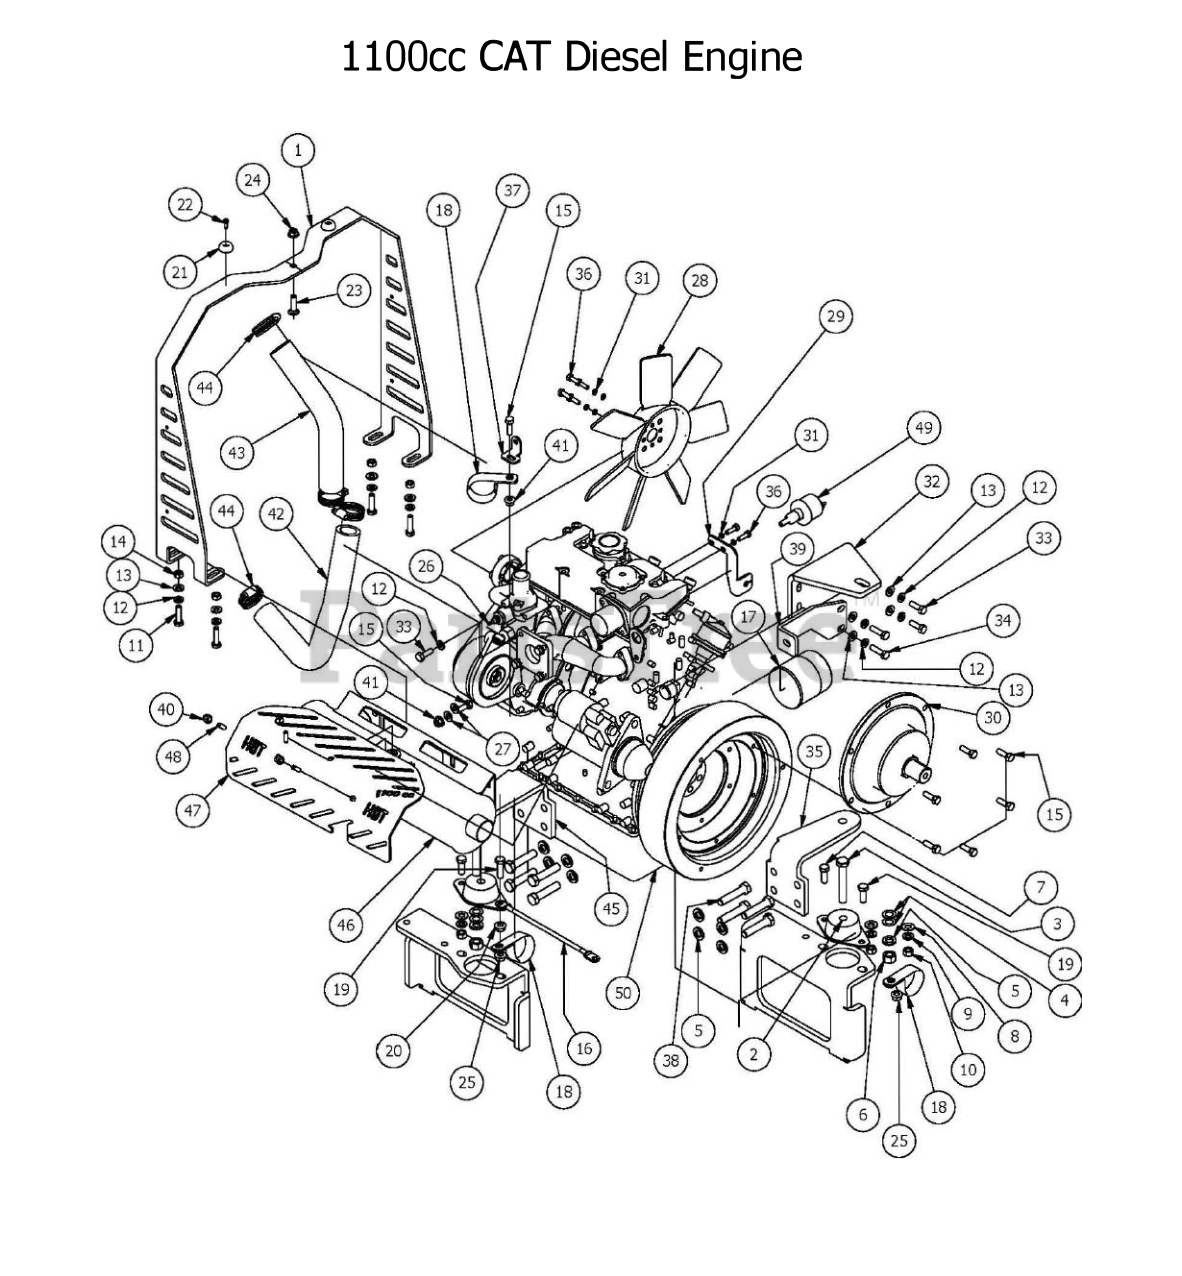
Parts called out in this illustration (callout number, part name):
1	Hood Holder Diesel
2	Rubber Isolator
3	1/2" x 3" Hex Bolt
4	1/2" Brass Washer
5	1/2" Lock Washer
6	1/2" Hex Nut
7	3/8" x 1" Hex Bolt
8	3/8" Flat Washer
9	3/8" Lock Washer
10	3/8" Hex Nut
11	5/16" x 1 1/4" Hex Bolt
12	5/16" Lock Washer
13	5/16" Flat Washer
15	5/16" x 1" Bolt
16	Starter to Chassis Cable - Diesel-35 Hp
17	CAT Oil Filter
18	Diesel Clamp 1 3/4" Vinyl
19	3/8" x 1 1/2" Hex Bolt
20	3/8" Flange Nut
21	Button Bumper
22	#10 x 1/2" Self Tapping Screw
23	5/16" x 1 1/4" Carriage Bolt
24	5/16" Nylon Flange Nut
25	3/8 Nylock Jam Nut 1/2 Nut
26	Temperature Sender-2012 Gauge
27	1/4 USS Flat Washer Zinc
28	Engine Fan
29	Diesel Throttle Bracket (4 Tier)
30	Stub Shaft
31	1/4" Lock Washer
32	Air Cleaner Support Diesel
33	M8 x 1.25 x 25mm Hex Head Bolt
34	M8 x 1.25 x 30mm Hex Head Bolt
35	Diesel Motor Side Support
36	6mm x 20mm Bolt
37	Diesel Radiator Hose Clamp Bracket
38	12mm Bolt- Diesel
39	Muffler Brace Diesel
40	1/4-20 Nylon Insert flange Nut
41	5/16" Flange Nut
42	Bottom Radiator Hose for Diesel
43	Top Radiator Hose for Diesel
44	1 1/8" Hose Clamp
45	Diesel Side Motor Mount (Left)
46	28/35hp Caterpillar Muffler
47	Diesel Muffler Guard (28hp)
48	1/4" x 3/4" Set Screw
49	oil pressure guage sender
50	1100cc CAT Diesel
